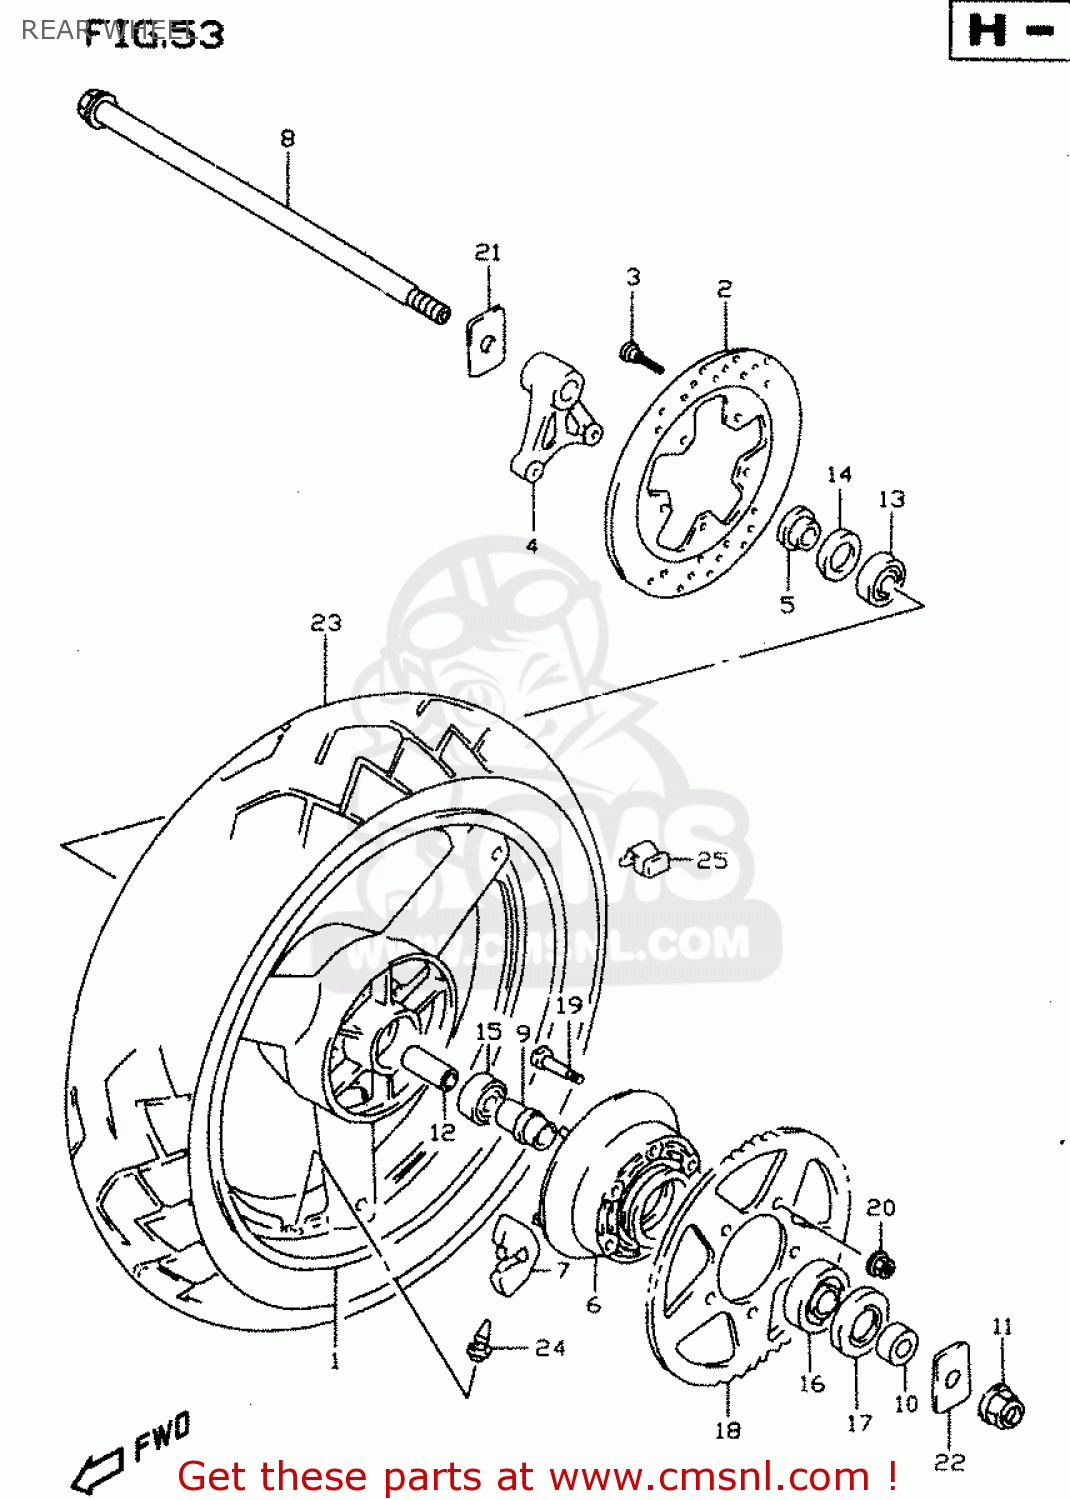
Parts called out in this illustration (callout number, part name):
1	WHEEL,REAR (MT5.50X17)(S
2	DISC,RR BRAKE
3	BOLT 8X33
4	BRACKET,RR CALIPER
5	SPACER,RR AXLE,R
6	DRUM,RR SPROCKET
7	ABSORBER,RR HUB SHOCK
8	AXLE,RR
9	RETAINER,RR HUB BEARING
10	SPACER,RR AXLE,L
11	NUT ,18MM
12	SPACER,RR WHEEL HUB BEARING
13	BEARING(20X47X14)
14	SEAL,OIL(28X47X7)
15	BEARING(20X47X14)
16	BEARING(25X62X17)
17	SEAL,OIL(35X62X8)
18	SPROCKET,RR(NT:42)
19	BOLT
20	NUT
21	WASHER,CHAIN ADJUSTER
22	WASHER,CHAIN ADJUSTER
23	TIRE,170/60ZR1
24	VALVE ASSY,WHEEL RIM(TR412)
25	BALANCER,WHEEL (10G)
